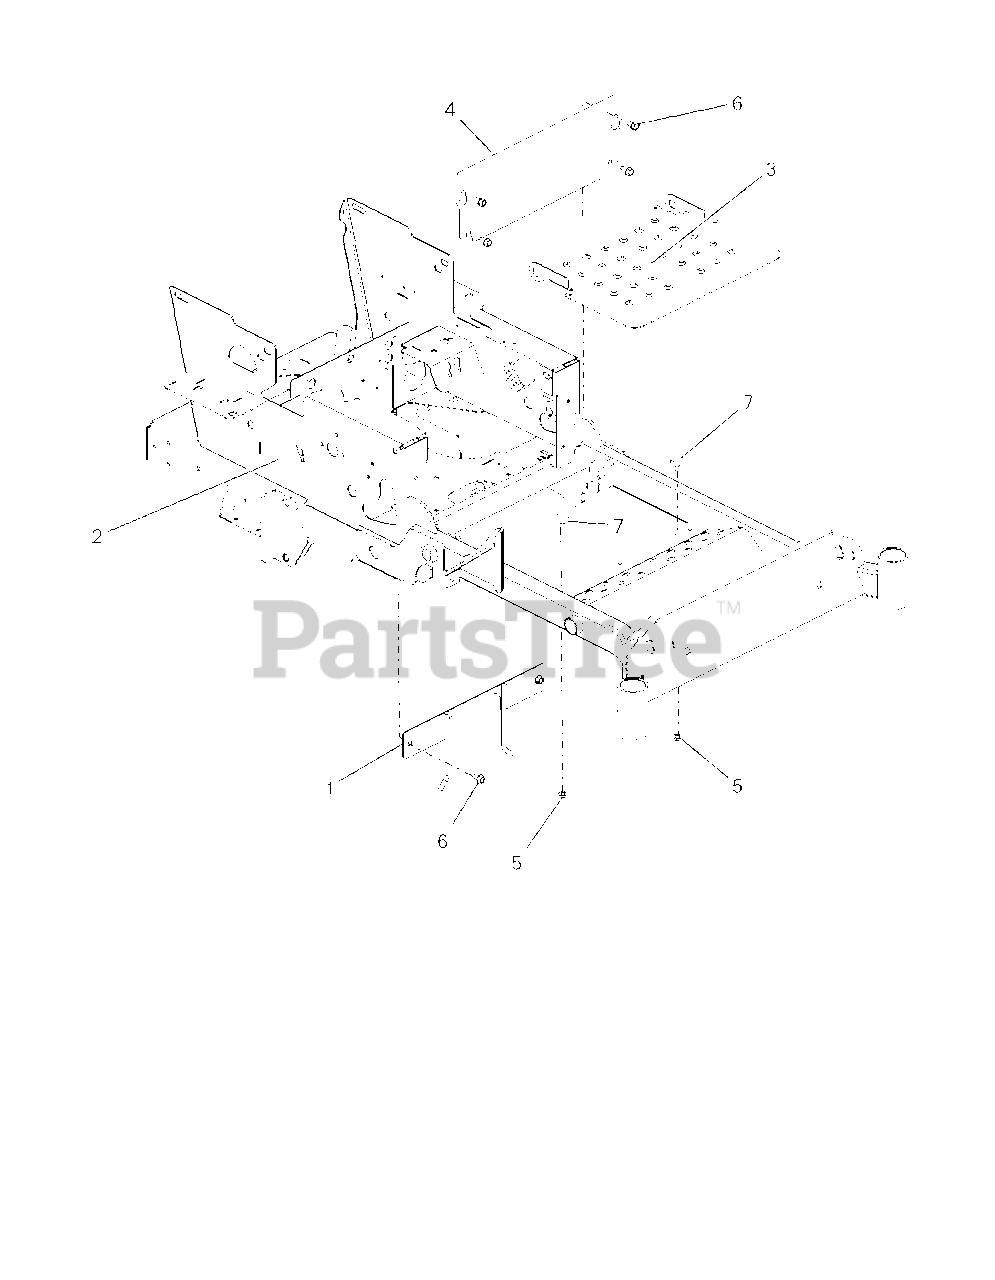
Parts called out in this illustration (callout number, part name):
1	WLDMT, PTO BELT FINGER-BLACK
2	WLDMT, 44"-48" HD FRAME
3	PANEL, INSPECTION
4	PLATE, KICK (RED)
5	@NUT-SPNLK-FLG .312-18 YWZC
6	SCR-TAP .38-16X.75 HWH TR YWZ
7	BUMPER, RUBBER
